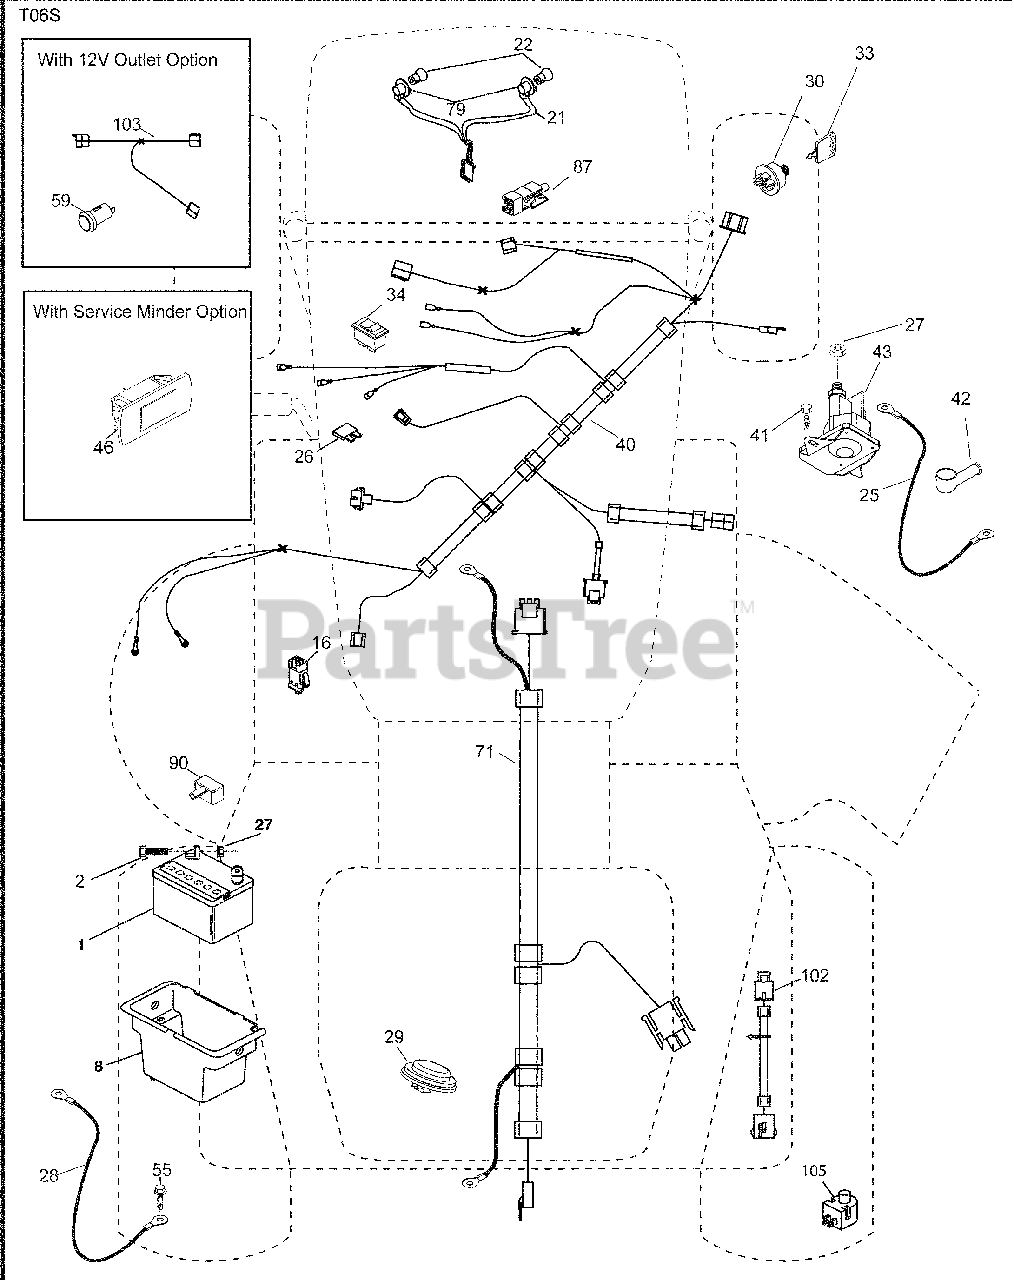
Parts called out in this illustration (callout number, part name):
1	Battery
2	Bolt Hex Head 1/4-20 x 3/4
8	Box Battery
16	Switch Interlock Push-In
21	Harness Socket Light w/4152J
22	Bulb Light
25	Cable Starter
27	Nut Keps Hex 1/4-20 unc
28	Cable, Ground
29	Switch, Seat
30	Switch, Ign
33	Key/Chain
34	Switch Light/Reset
40	Harness Ign. Dash
41	Screw Thd Cut 1/4-20 x 1/2
42	Cover, Terminal
43	Solenoid
46	Gauge Serviceminder Hrmtr
55	Screw Thdrol 5/16-18 x 3/4 TYTT
71	Harness Ign.
79	Socket Asm. Bulb
87	Switch Interlock
90	Cover Terminal
102	Harness Pigtail
105	Switch Reverse
